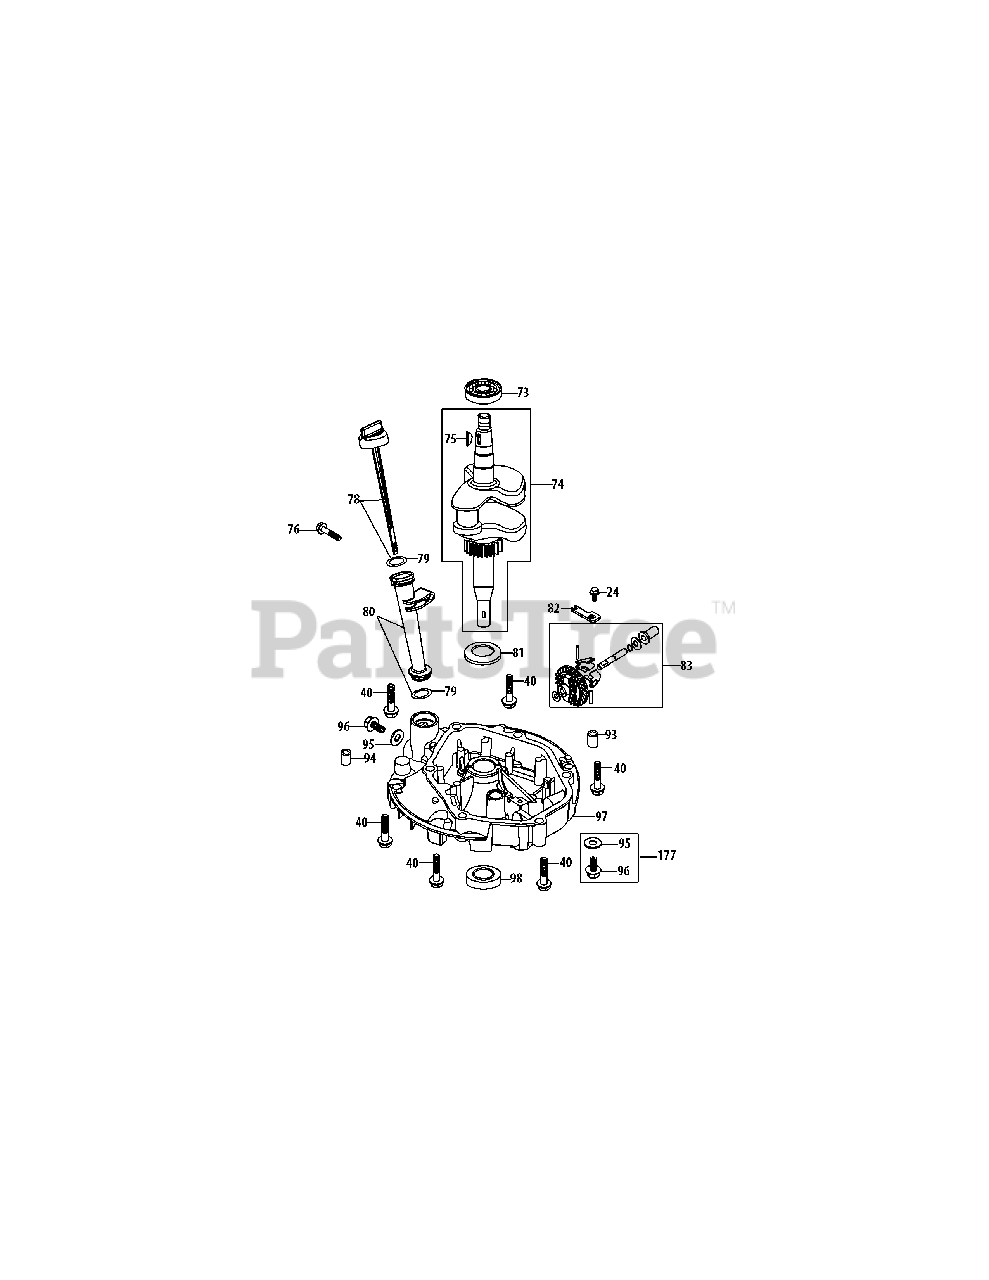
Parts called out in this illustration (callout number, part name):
24	Bolt M6X14
40	Bolt M8X50
73	Main Bearing
74	Crankshaft Assembly
75	Woodruff Key
76	Bolt M6X35
78	Dipstick Assembly
79	Dipstick / Oil Fill Tube O-Ring
80	Oil Filler Tube Assemlby
81	Crankshaft Thrust Washer
82	Governor Gear Mounting Plate
83	Governor Gear/Shaft Assembly
93	Crankcase Cover Dowel Pin 7×14
94	Crankcase Cover Dowel Pin 9×14
95	Oil Drain Plug Washer
96	Oil Drain Plug
97	Crankcase Cover
98	Lower Crankshaft Seal
177	Oil Drain Plug And Washer Assy
